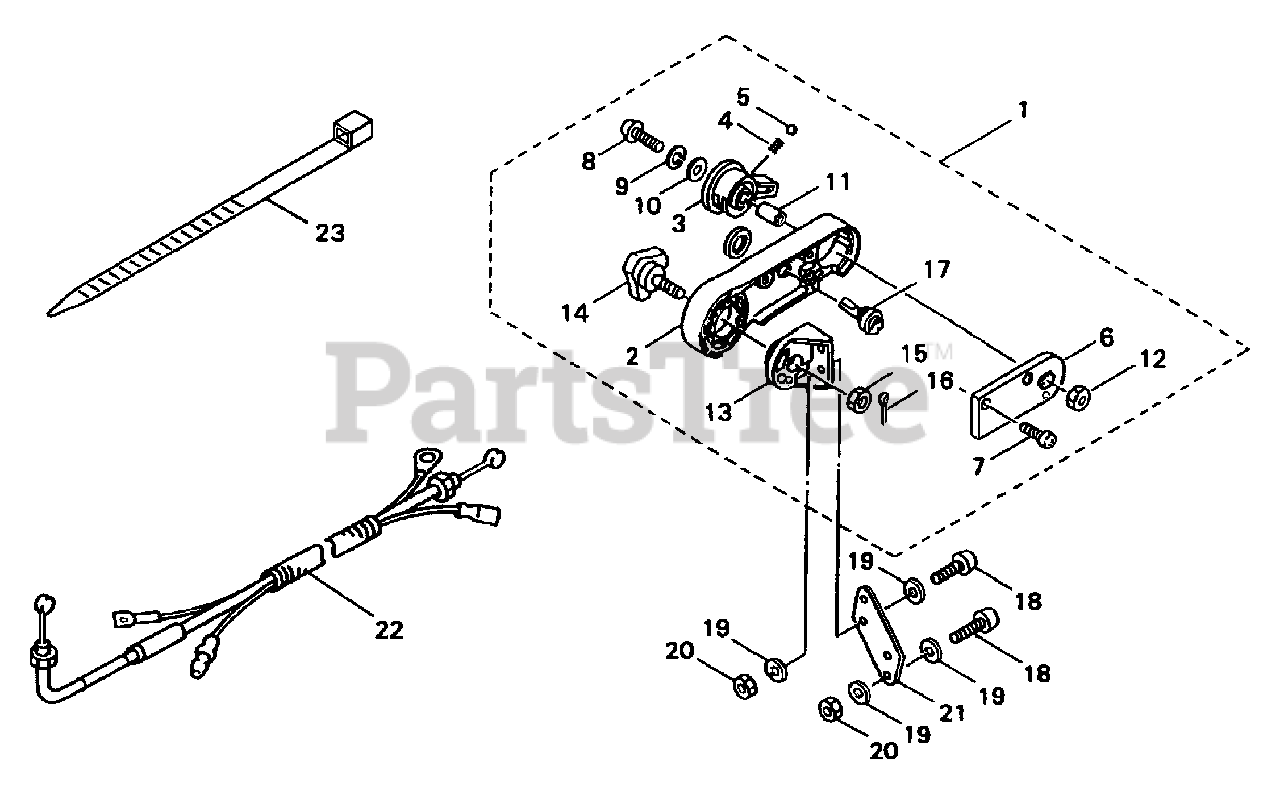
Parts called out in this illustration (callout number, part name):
1	Throttle Lever Assembly
7	Screw-Tapping
9	Washer-Spring
14	Bolt-Knob
15	Nut-Nylon
16	Pin-Cotter
22	Throttle Cable Assembly
